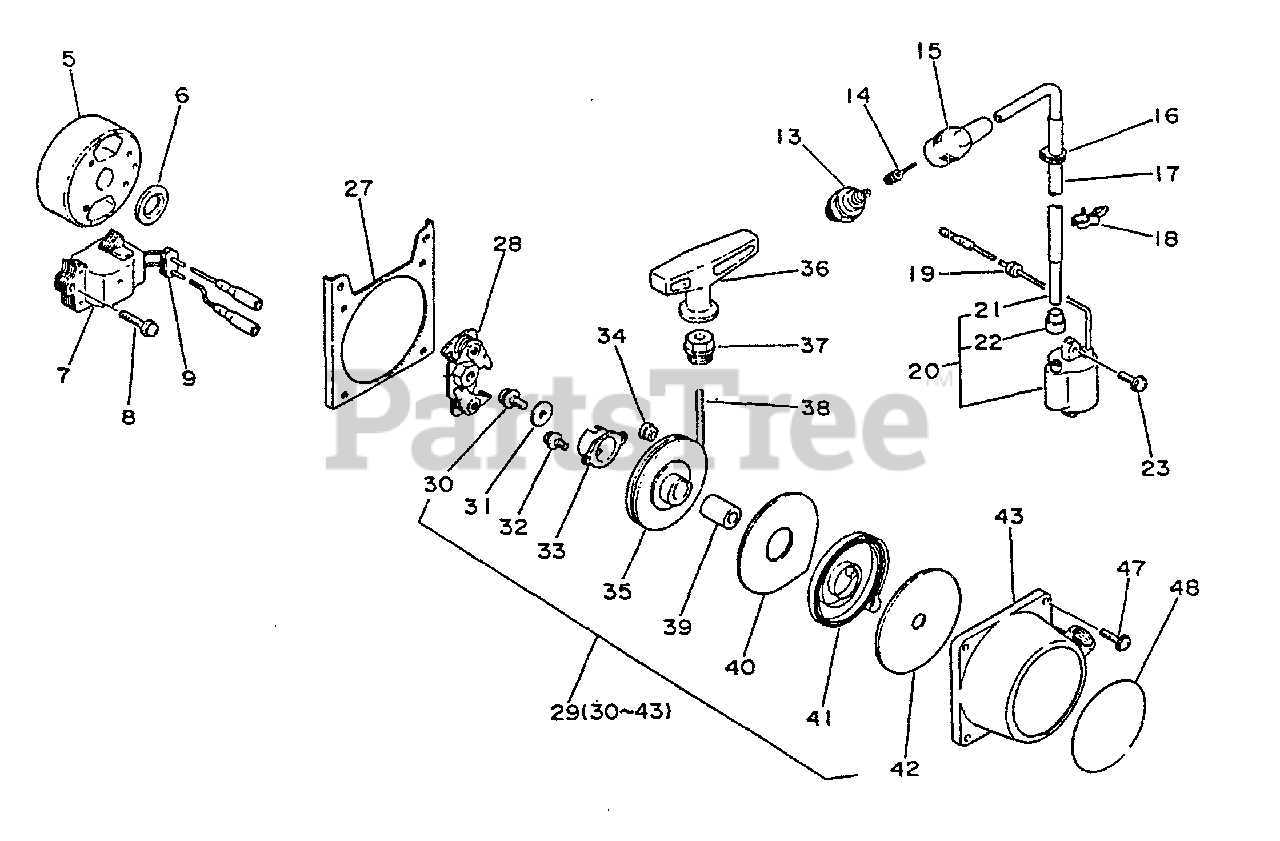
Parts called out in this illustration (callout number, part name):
5	FLYWHEEL
7	COIL, IGNITION
8	SCREW 4×20
13	SPARK PLUG - BPM7A
14	TERMINAL, SPARK PLUG
15	CAP, SPARK PLUG
17	TUBE, IGNITION COIL 6×8×340
20	COIL, IGNITION
21	CORD, HIGH TENSION
23	SCREW 4×14
28	PAWL ASSY, STARTER
29	STARTER ASSY
30	SCREW 5×10
31	WASHER 5.2×16×1.0
32	SCREW 4×8
33	PAWL CATCHER
34	CLIP, STARTER ROPE
35	REEL, ROPE
36	GRIP, STARTER
37	GUIDE, ROPE
38	ROPE, STARTER 3.5×850
40	PLATE, SIDE
41	SPRING, RECOIL
42	PLATE, SIDE
43	CASE, RECOIL STARTER
47	SCREW 4×16
48	LABEL - ECHO
